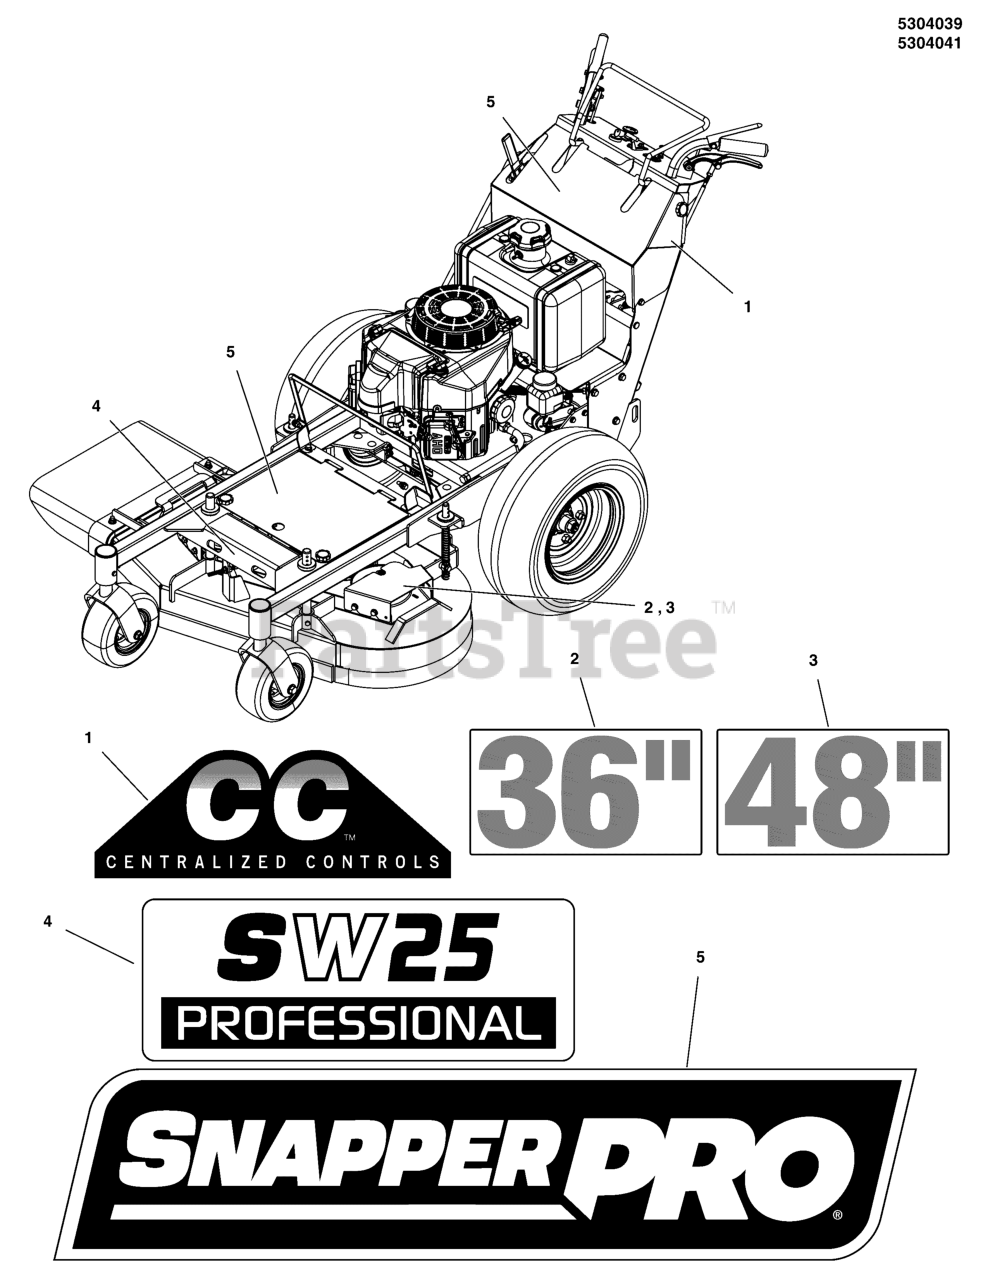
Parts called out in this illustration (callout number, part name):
1	DECAL, CENTRALIZED CONTROLS
2	DECAL, 36
3	DECAL, 48
4	DECAL, MODEL SERIES, SW25
5	DECAL, SNAPPER PRO LOGO, LARGE
